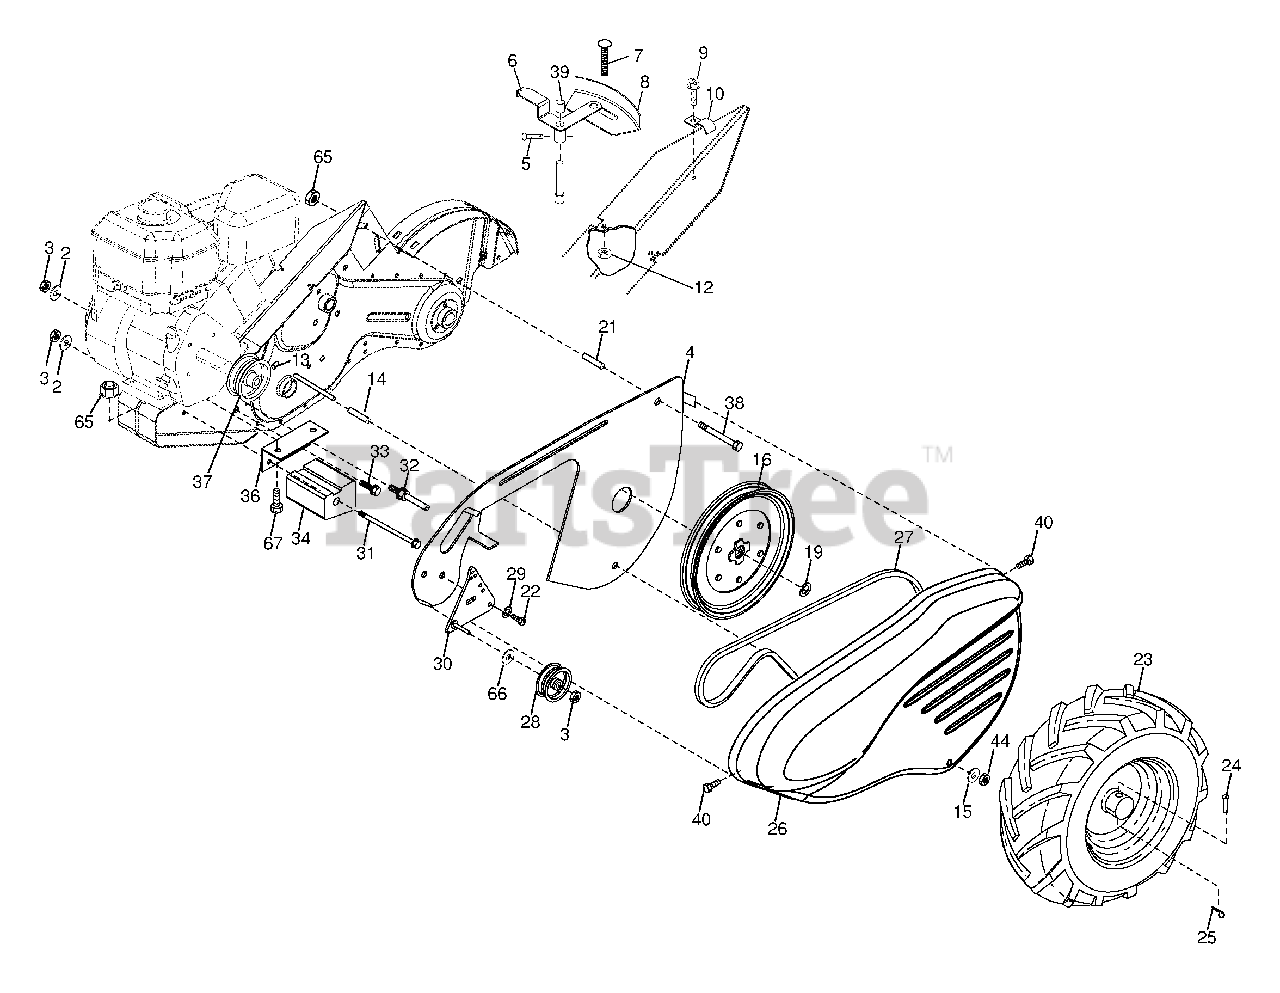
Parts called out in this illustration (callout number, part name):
1	Nut, Hex, Flangelock 5/16
2	Washer, Lock 3/8
3	Nut, Hex 3/8-16
4	Shield, Inner Belt Guard, RH
5	Pin, Spiral, Flared
6	Lever, Shift
7	Bolt, Carriage, Grade 5 1/4-20 x 1/2
8	Plate, Shift Indicator
9	Screw, Slotted, Hex Washer Head #10-24 x 1/2
12	Nut, Hex, Keps 1/4-20
13	Set Screw, Hex 5/16-18 x 3/8
14	Spacer, Split 0.327 x 0.42 x 2.09
15	Washer 11/32 x 11/16 x 16 Gauge
16	Sheave, Transmission
19	Retainer Ring
21	Spacer, Split
22	Bolt, Hex Head 5/16-24 x 1/2
23	Rim
23	Valve, Tire
24	Rivet, Drilled
25	Clip, Hairpin
26	Guard, Belt
27	Belt, V
28	Pulley, Idler
29	Ring, Klip
30	Bracket, Idler
31	Bolt, Hex Head 5/16-16 x 12
32	Shaft, Idler Arm
33	Bolt, Hex 3/8-16 x 1
34	Counterweight, LH
35	Bolt, Hex Head 5/16-18 x 1-1/2
36	Bracket, Reinforcement, LH
37	Sheave, Engine
38	Bolt, Hex Head 5/16-18 x 2-3/4
39	Cap, Plunger, Black
40	Screw, Slotted, Hex Washer Head #10-24 x 1/2
44	Locknut, Hex, with Insert 5/16-18
65	Nut, Hex, Flangelock
66	Washer 13/32 x 13/16 x 12 Gauge
